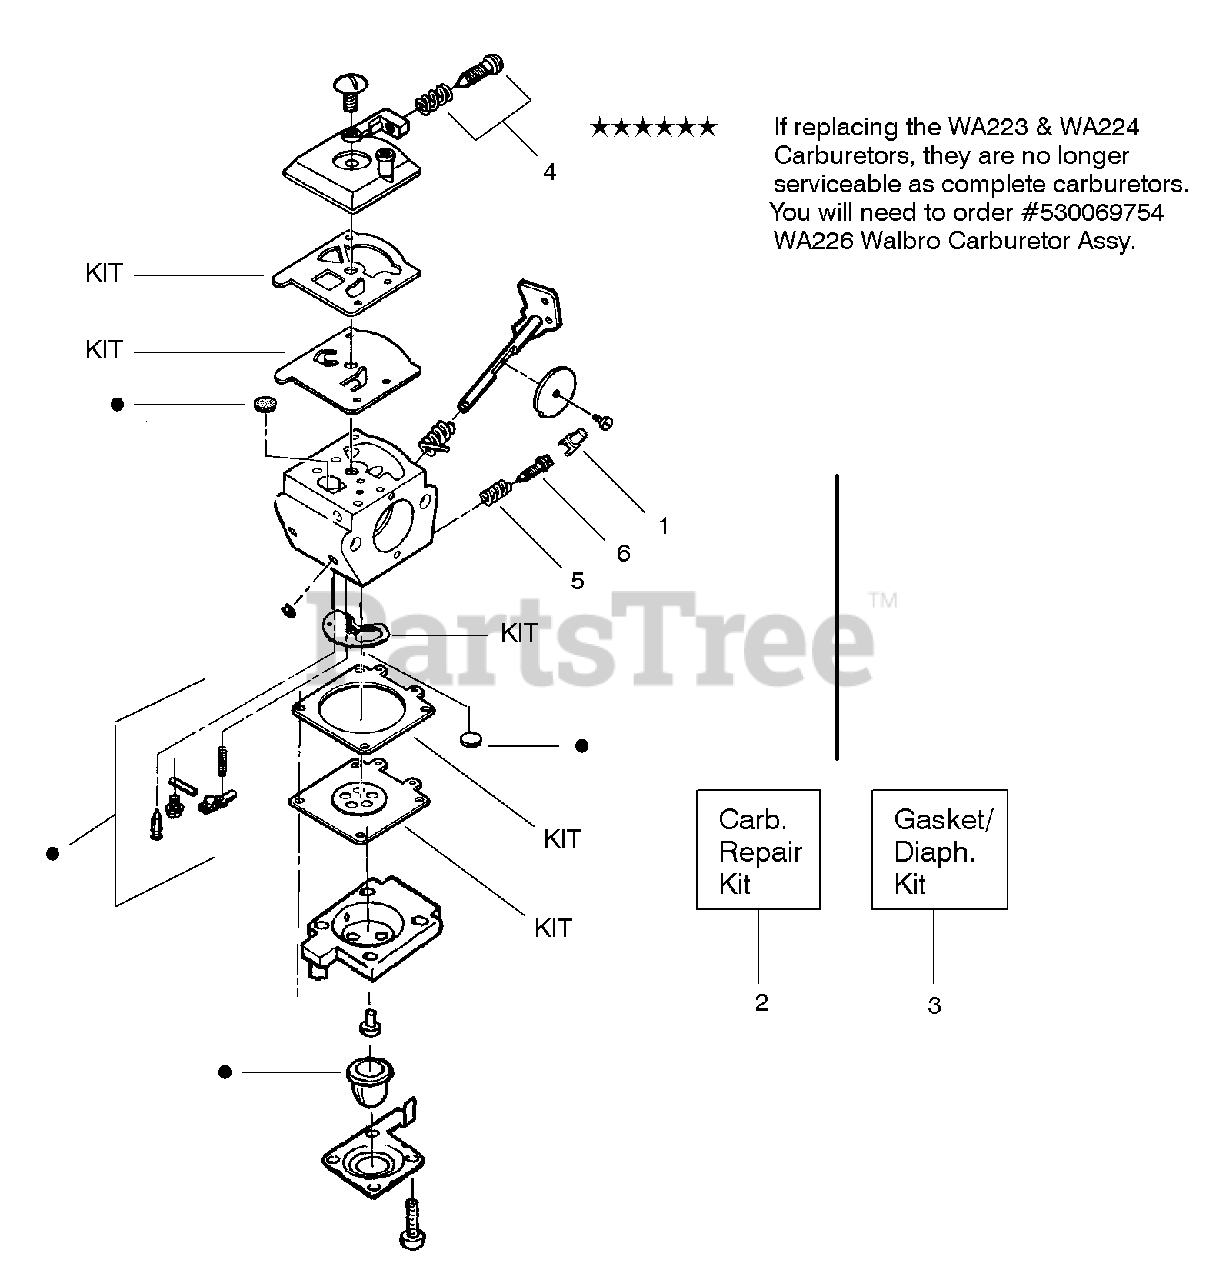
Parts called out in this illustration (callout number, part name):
1	Limiter Cap
2	Carburetor Repair Kit WA223
3	Gasket/Diaphragm Kit WA223, WA224 & WA226
4	Idle Screw & Spring Kit
5	Low Speed Spring
6	Low Speed Needle
530069754	KIT-CARBURETOR ASSY
